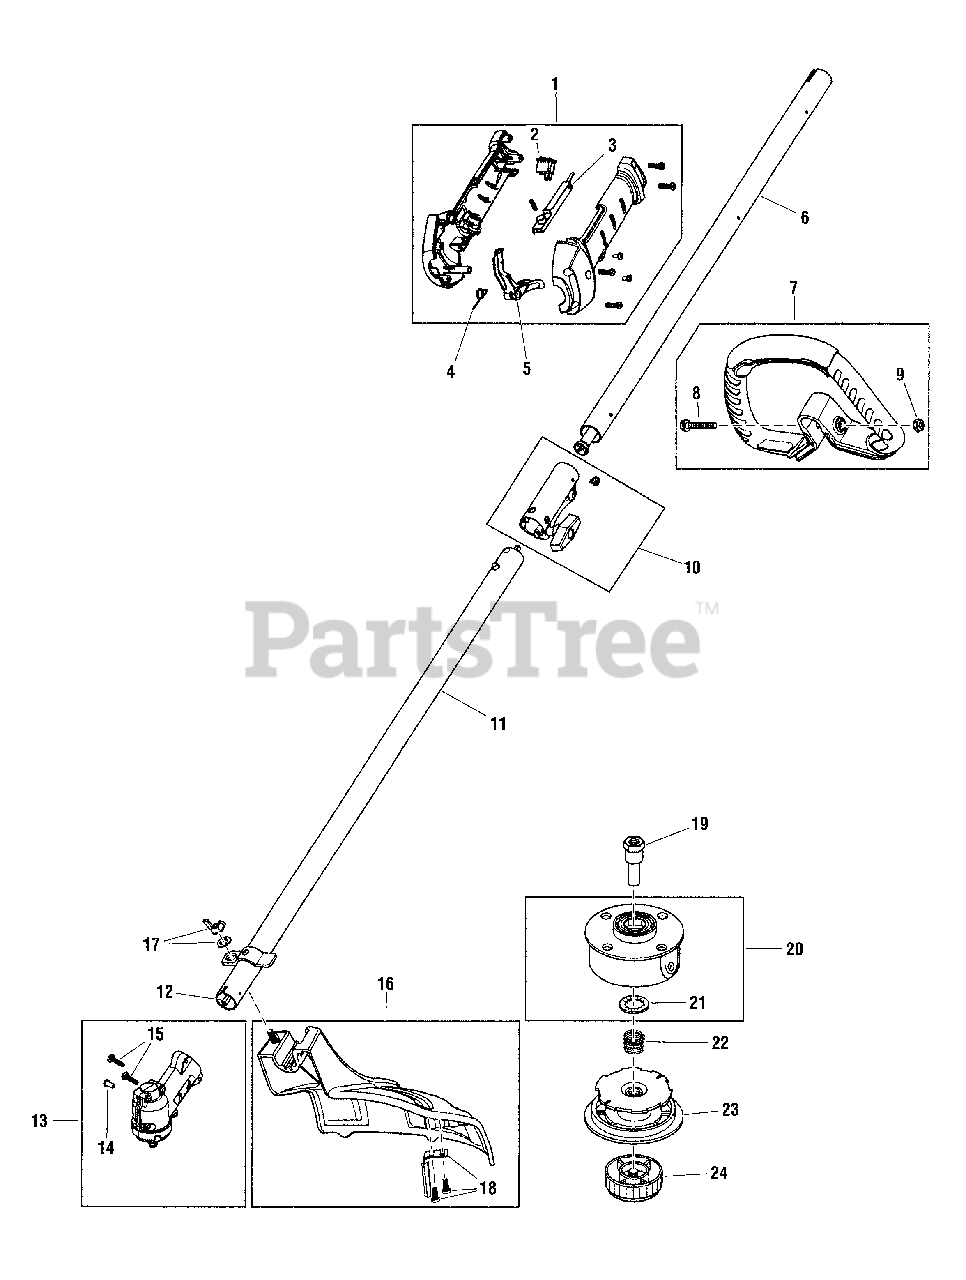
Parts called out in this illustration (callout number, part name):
1	ASSEMBLY, Throttle Housing
2	ASSEMBLY, Trigger Switch
3	LOCK-OUT, Throttle
4	SPRING, Throttle Trigger
5	TRIGGER, Throttle
6	ASSEMBLY, Upper Drive Shaft
7	ASSEMBLY, D-Handle
8	BOLT
10	COUPLER, Split Boom
11	ASSEMBLY, Lower Shaft Housing
12	DRIVE SHAFT, Lower Flexible
13	ASSEMBLY, Gearbox
14	SCREW, Anti-Rotation
15	HARDWARE, Gearbox Mounting
16	ASSEMBLY, Shield
17	HARDWARE, Shield Mounting
19	SHAFT, Spool
20	ASSEMBLY, Outer Spool
21	RETAINER
23	REEL, Inner
24	ASSEMBLY, Bump Head Knob
